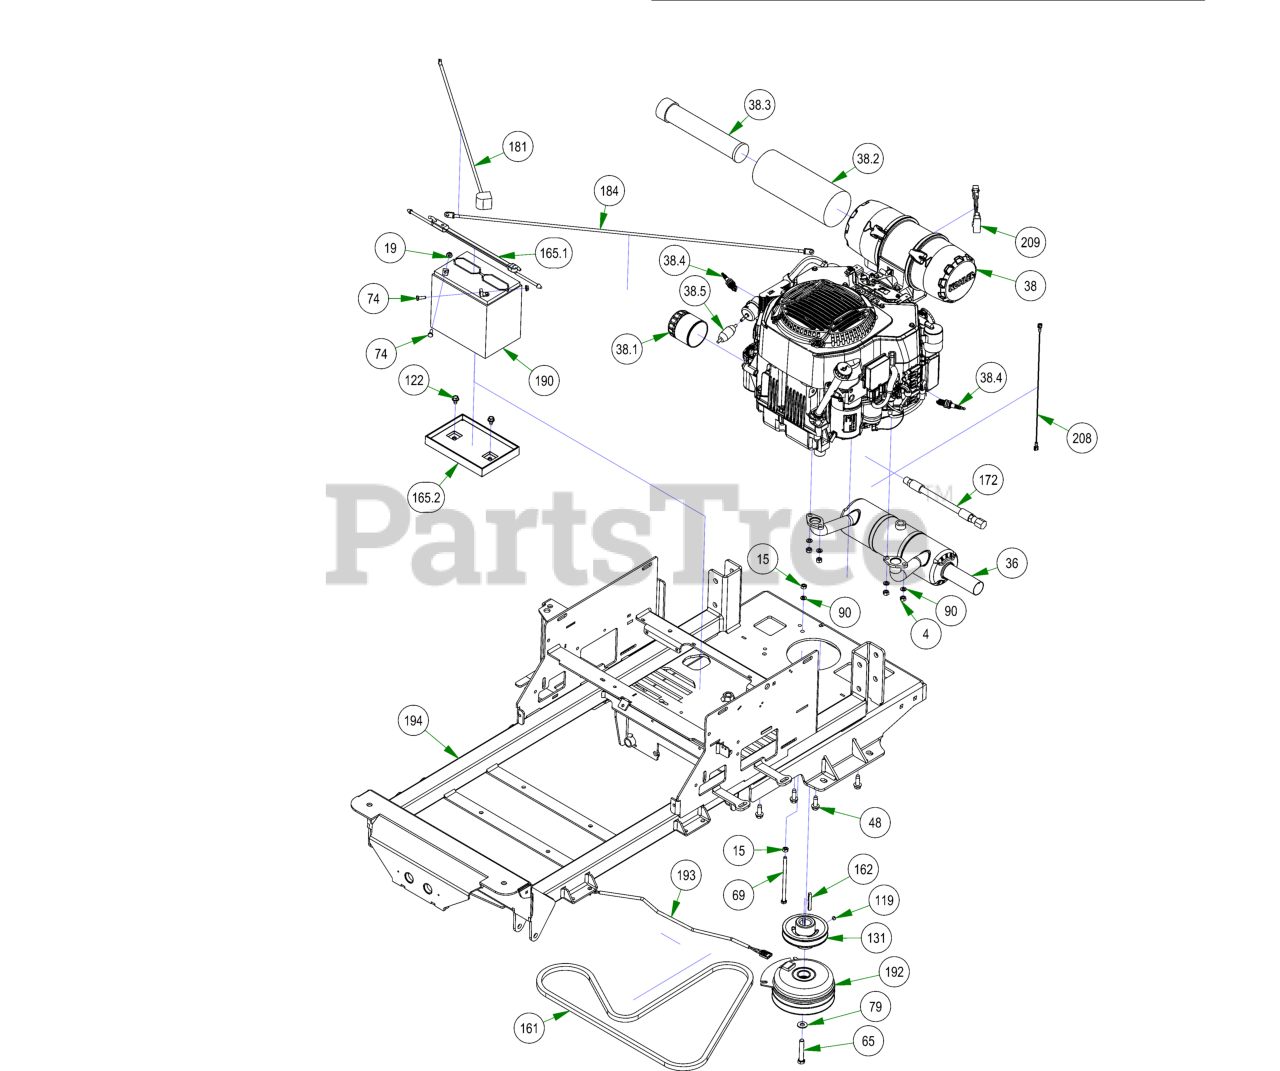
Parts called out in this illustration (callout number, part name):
4	M8-1.25 DIN 934 HEX NUT (CL.8) ZINC
15	5/16-18 HEX NUT ZINC
19	1/4-20 HEX SERRATED FLANGE NUT HARD/ZINC
36	2023 ECV749 Maverick HD Muffler
38	Kohler Command 26.5hp - EFI
38.1	Oil Filter
38.2	Outter Air Filter
38.3	Inner Air Filter
38.4	Spark Plug
38.5	25/26 HP Kohler Fuel Filter
48	3/8-16 X 1-1/8 HEX WASHER UNSLOT SERRATED (TRI-LOB) TRS ZINC YELLOW
65	7/16-20 X 2-1/2 HEX Bolt GR 8 W/ Patch
69	5/16-18 X 5-1/2 HEX CAP SCREW (GR.5) ZINC
74	1/4-20 X 3/4 HEX CAP SCREW (GR.5) ZINC
79	3/8 FLAT WASHER USS (1" OD) ZINC
90	5/16 SPLIT LOCKWASHER ZINC
119	5/16-24 X 1/4 SOCKET SET SCREW (CUP PT) PLAIN
122	5/16-18 X 1/2 HWH unslot (F) tcs zinc
131	4 3/4 Motor Pulley
161	75.8" Pump Belt
162	1/4 X 2 SQ MACHINERY KEY 1018 STL PLAIN
165	2023 Battery Hold Down Assembly Strap
165.1	2023 Rubber Battery Hold Down Strap
165.2	Battery Tray
172	Oil drain Hose
181	24 inch Black Cable – MZ/ZT
184	36" Red Battery Cable
190	SP-35 Battery
192	Clutch Assembly
193	Clutch Pigtail
194	2023 Maverick Frame - Painted
208	Compact Outlaw/Honda Starter Jumper Wire
209	2019 Harness Adaptor-Carbureted Yamaha
